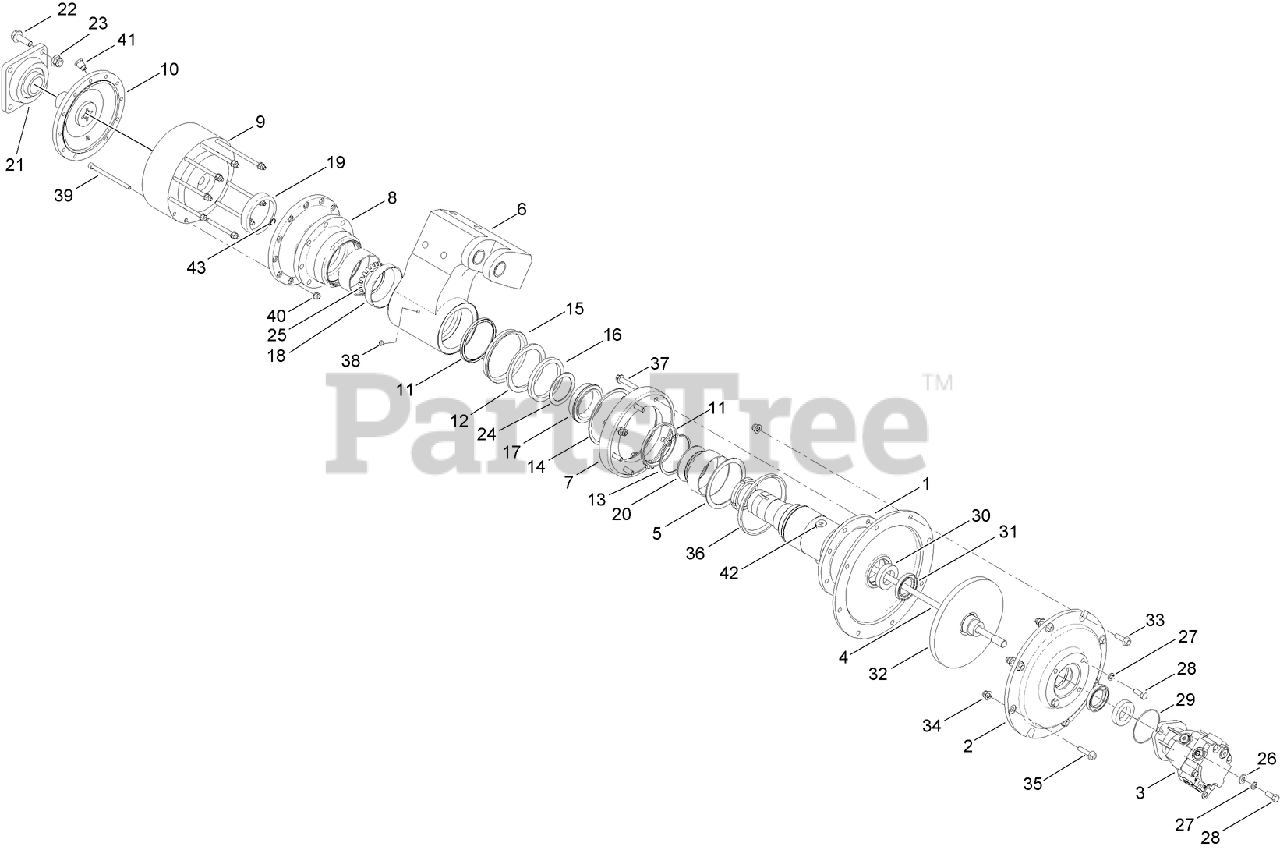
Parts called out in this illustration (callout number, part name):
1	PIVOT-BOOM
2	COVER-FLYWHEEL
3	HYD MOTOR ASM
4	SHAFT-DRIVE, TRENCHER
5	WASHER-THRUST, THIN
6	MOUNT-BOOM
7	SPACER-PIVOT, BOOM
8	HUB-SPROCKET, DIGGING
9	GEARBOX-Planetary
10	COVER-PLANETARY
11	SEAL-Urethane
12	WASHER-THRUST, THICK
13	RING-RETAINING, EXTERNAL
14	RING-WEAR
15	SEAL-PLANETARY, URETHANE
17	BEARING
18	BEARING
19	CUP-BEARING
20	BEARING-CONE
21	BEARING
22	SCREW-FLANGE
23	NUT-HHF
24	WASHER-Shim
25	WASHER-LOCK, BEARING
27	WASHER-LOCK
28	SCREW-HH
30	BEARING-Ball
31	SEAL-Flywheel
32	FLYWHEEL-DRIVE, TRENCHER
34	NUT-HHF, LOCK
35	SCREW-HHF
36	SEAL-URETHANE
37	SCREW-HHF
38	FITTING-GREASE
39	SCREW-HSH
40	NUT-LOCK, NI
41	PLUG-PIPE
42	PLUG-FREEZE
43	RING-RETAINING, INTERNAL
